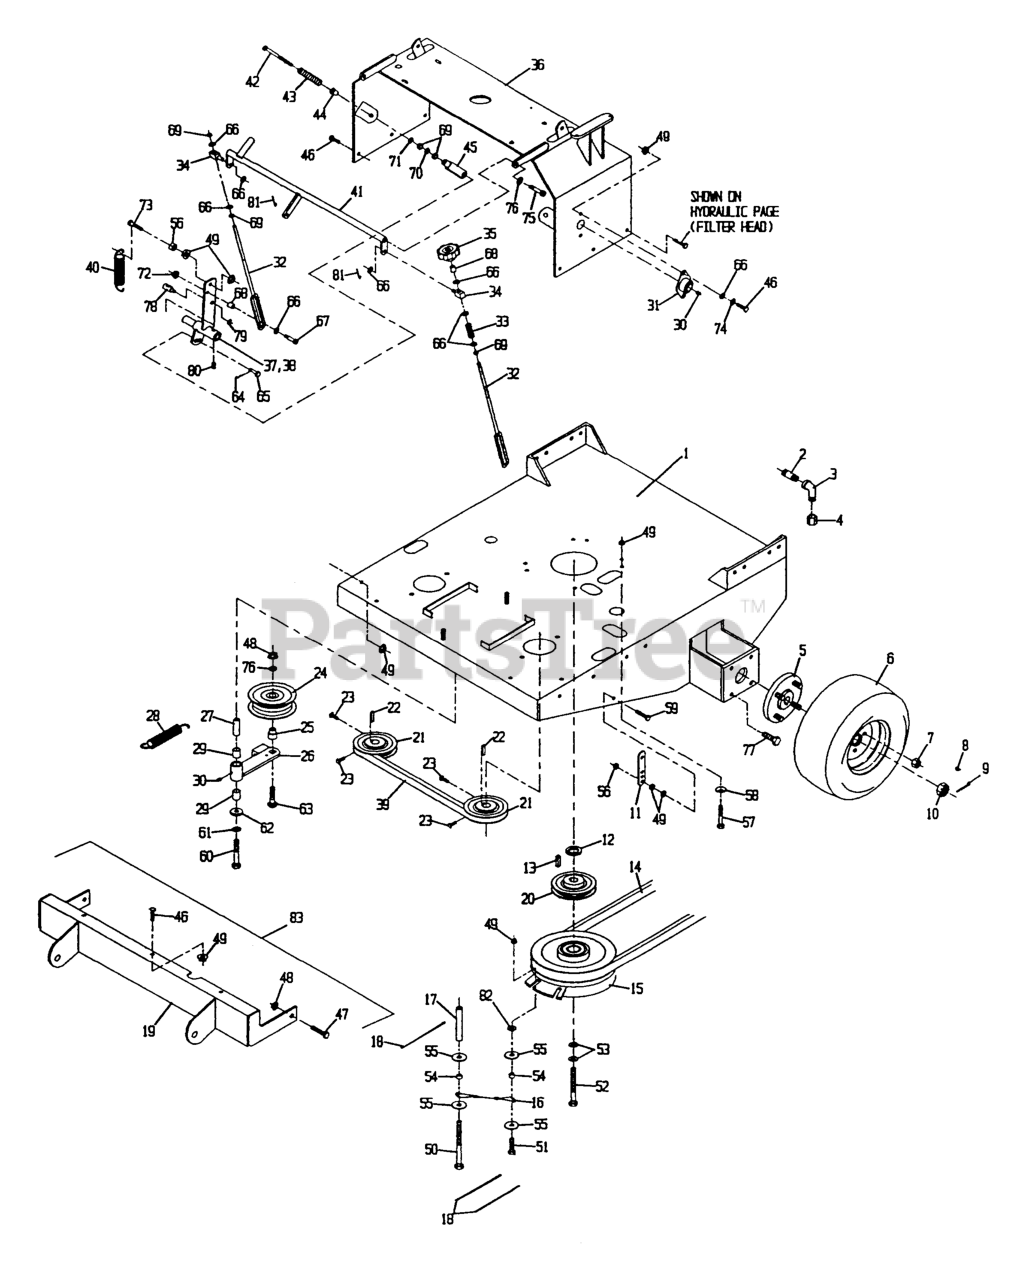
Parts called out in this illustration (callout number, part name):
1	Engine Deck Weldment
2	NIPPLE,PIPE
3	ELBOW-90 DEG
4	CAP-HEX
8	KEY-WOODRUFF
9	PIN-COTTER
11	TAB-SPRING, EXTENSION
14	Kit, Belt/Shield
17	SPACER-SHIELD
18	TIE-CABLE
19	WLD,SULKY HITCH
21	SHEAVE - PUMP
23	SCREW-SET
25	BUSHING-IDLER
26	IDLER ARM ASM
27	BUSHING
28	SPRING-EXTENSION
29	SLEEVE-BEARING
31	BEARING-FLANGE, SIDE
33	SPRING-COMPRESSION
35	KNOB-TRACKING
39	BELT-HYDRO TRANS DR
40	SPRING-EXTENSION
41	WLD,CRANK SPEED CONTROL
42	BOLT-RETURN, NEUTRAL
43	SPRING-RETURN, NEUTRAL
44	BUSHING-FLANGED
45	YOKE-ADJUSTABLE
53	WASHER-SPRING
54	SPACER,CLUTCH ANCHOR
58	WASHER-SPRING
59	BOLT-TAP, HH
64	PIN-COTTER
65	PIN-CLEVIS
67	SCREW-HSH
74	WASHER-LOCK
75	SCREW-HSH
80	SCREW-SET
83	Hitch Kit, Sulky
